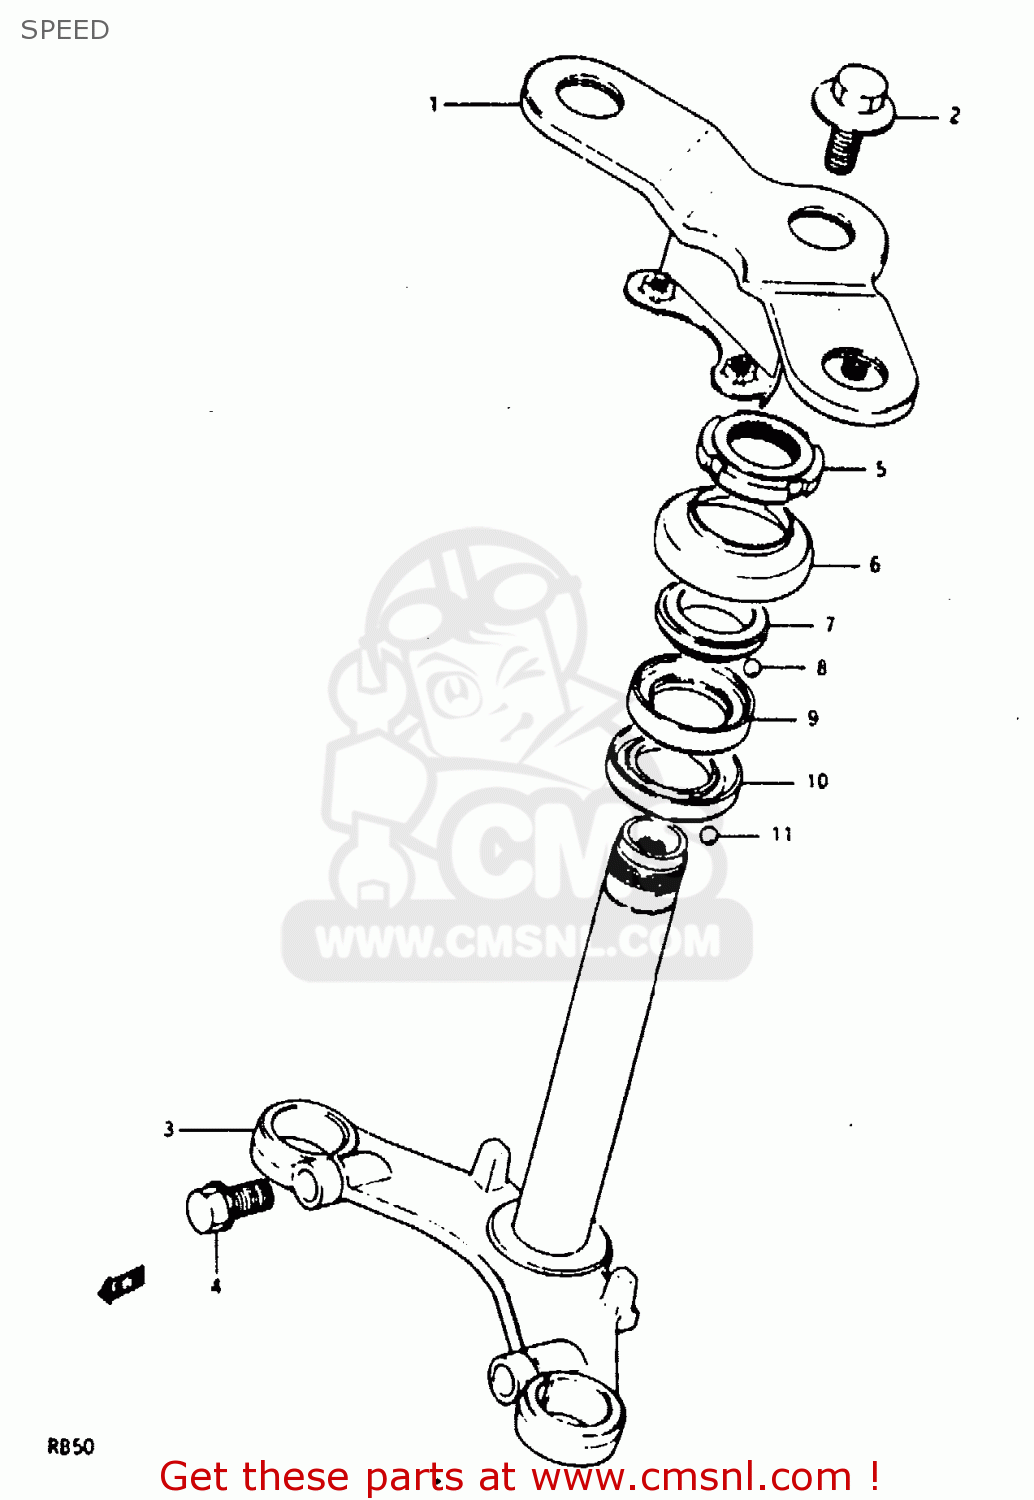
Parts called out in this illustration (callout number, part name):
1	HEAD,STEERING STEM
2	BOLT
3	STEM,STEERING
4	BOLT 10X30
5	NUT,STEERING STEM(25X44X10)
6	DUST SEAL,STEERING UPR
7	RACE,STEERING OUTER UPR
8	BALL
9	RACE,STEERING INNER UPR
10	LACE,STEERING INNER LWR
11	BALL
